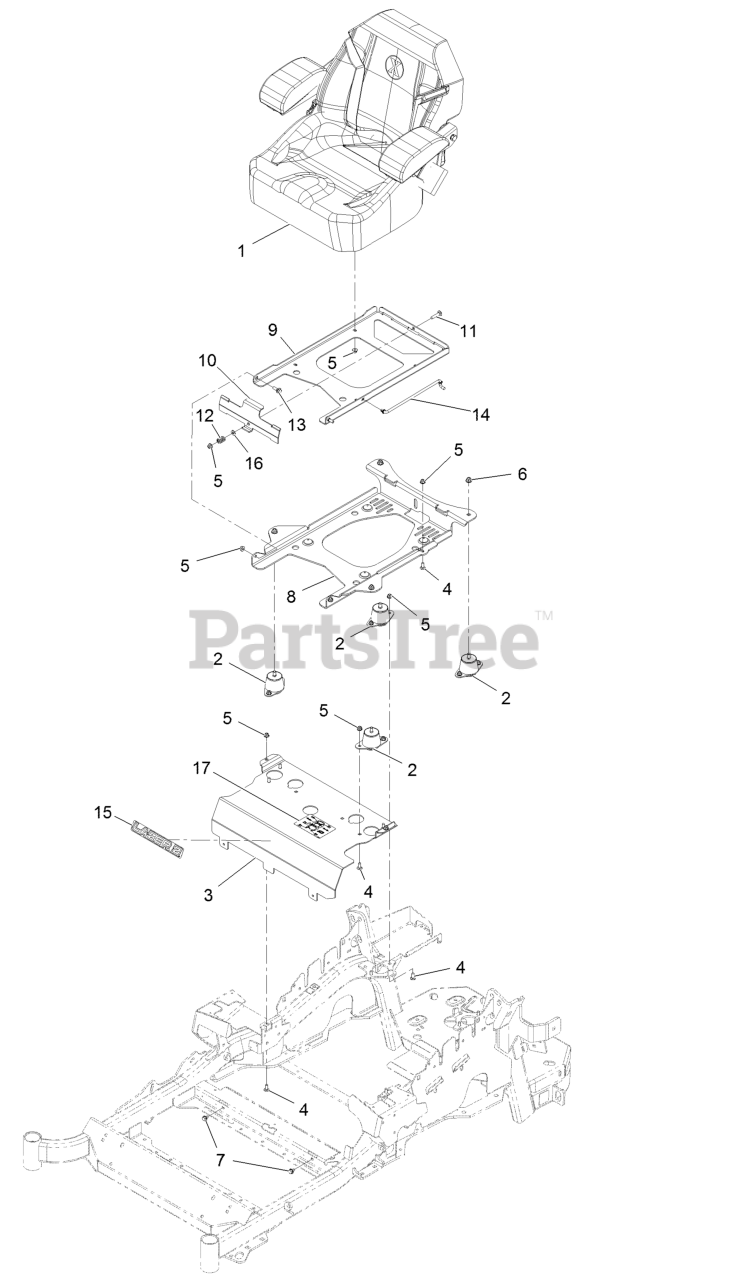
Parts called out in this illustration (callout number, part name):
1	Seat-Exmark Standard
2	Isolator-Seat
3	Panel,Seat Mount-Front
4	Bolt-Carriage 5/16-18 X 3/4 Short Neck
5	Nut-Nyloc 5/16-18 Flg
6	Nut-Nyloc 3/8-16 Flg
7	Screw-HWH 5/16 X 1/2 Tf
8	Plate-Tilt, Seat Support
9	Plate-Frame, Seat
10	Plate-Latch, Seat
11	Bolt-Carriage 5/16-18 X 1 1/2
12	Spring-Compression
13	Screw-Shoulder
14	Rod-Prop
15	Decal, Lazer Model
16	Washer-5/16 SAE
17	Decal-Service Aid
